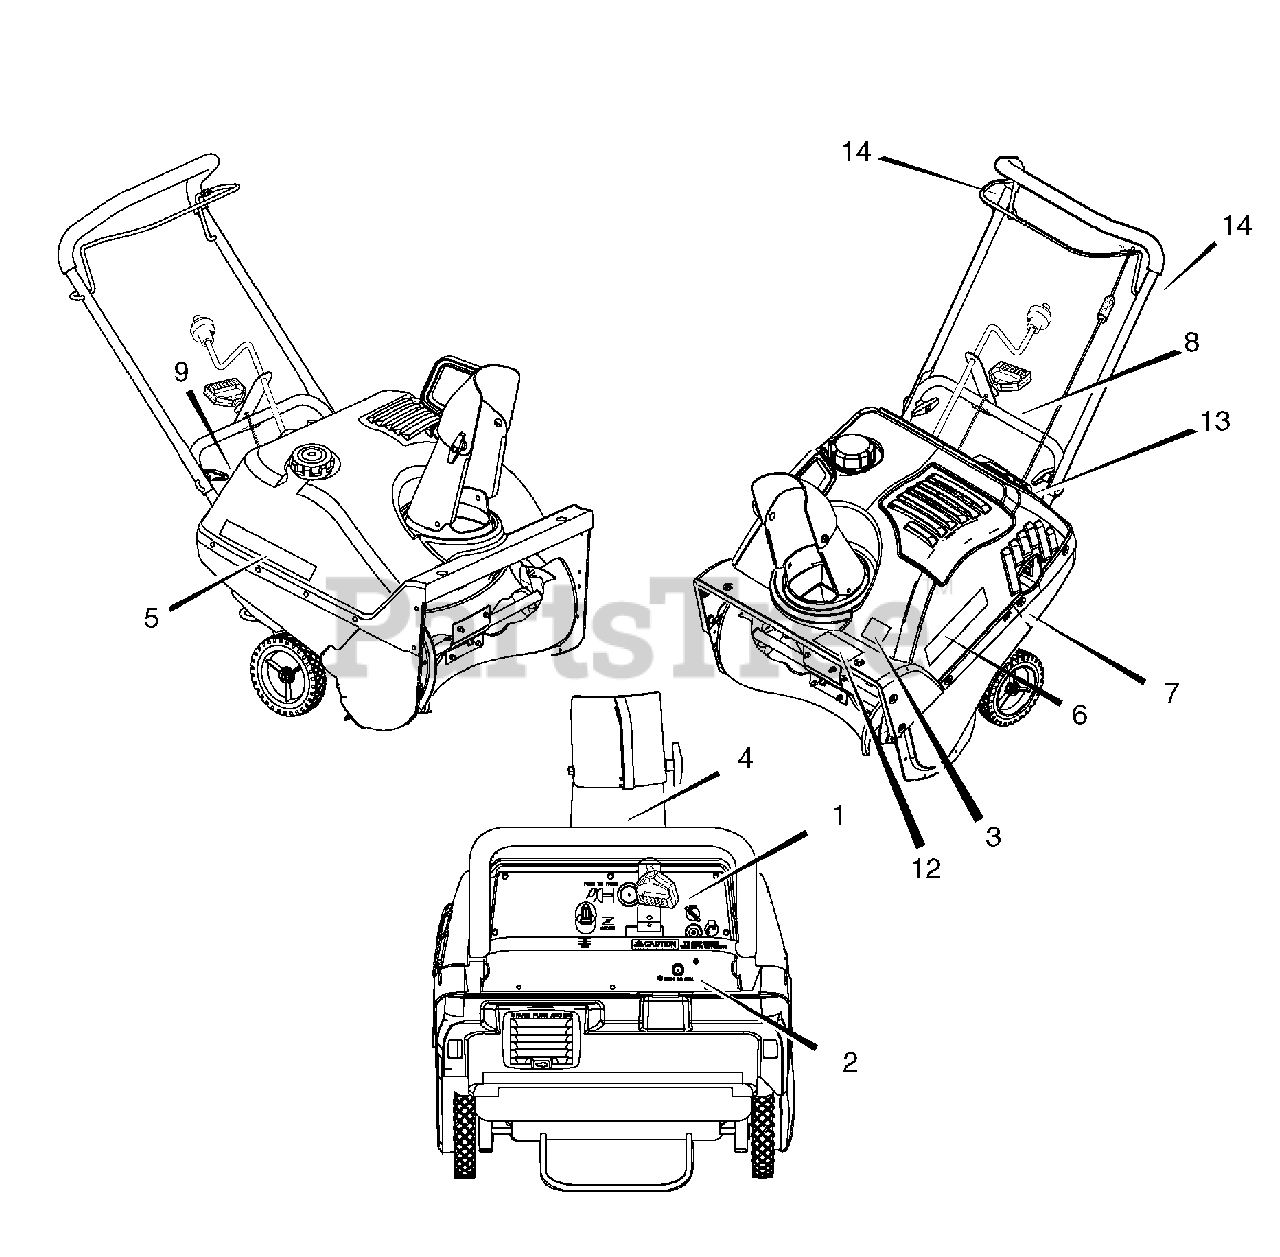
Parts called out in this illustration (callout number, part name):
1	DECAL, Control Panel Electric Start
2	DECAL, Electric Start
3	DECAL, Danger Auger
4	DECAL, Danger Chute
5	DECAL, 522 Snapper R.H.
6	DECAL, 522 Snapper L.H.
7	DECAL, Hot Muffler
8	DECAL, Auger Control
9	DECAL, Choke
12	DECAL, 522E
13	DECAL, Warning, Access Cover
14	DECAL, Handle protector
15	MANUAL, Operator's
